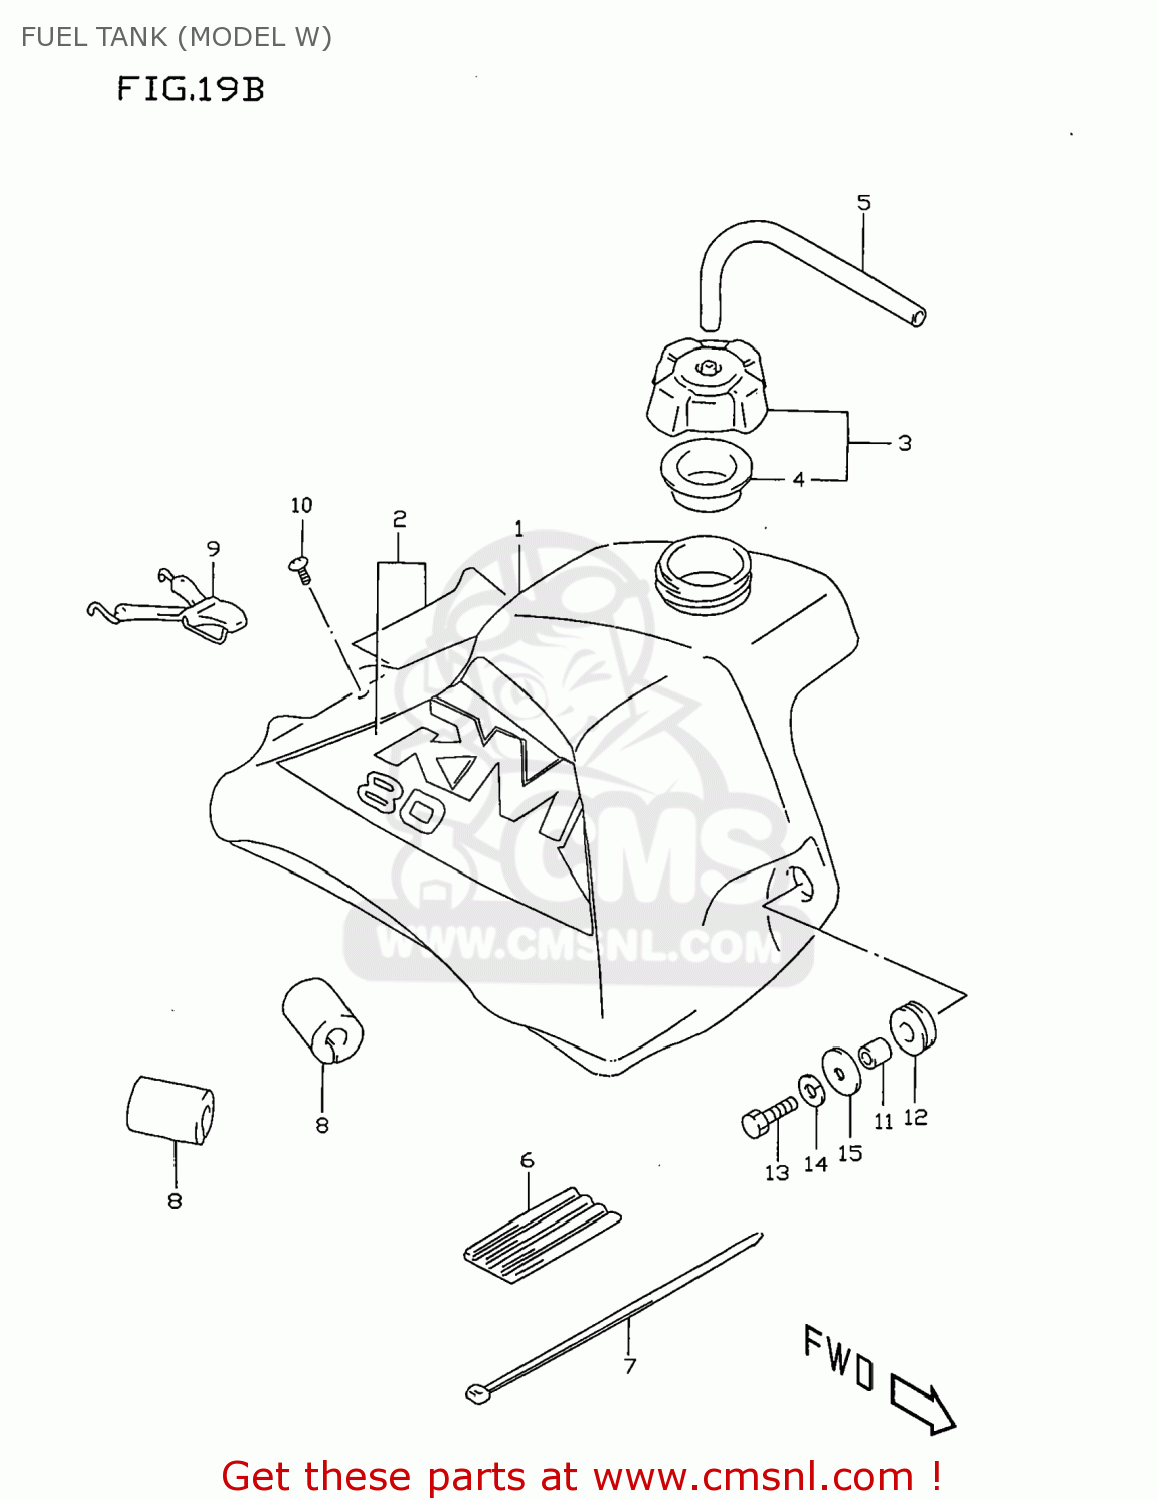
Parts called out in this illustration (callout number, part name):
1	TANK,FUEL(YELLOW)
2	TAPE SET,FUEL TANK
3	CAP SET,FUEL TANK
4	GASKET,CAP (NAS)
5	HOSE(5X8.2X600)
6	CUSHION,FUEL TANK UPR FR
7	CLAMP(L:250)
8	CUSHION,FUEL TANK UPR RR
9	BAND,FUEL TANK RR
10	SCREW
11	SPACER(6.5X10X11.5)
12	CUSHION
13	BOLT
14	LOCK WASHER
15	WASHER(6.5X24X1.6)
